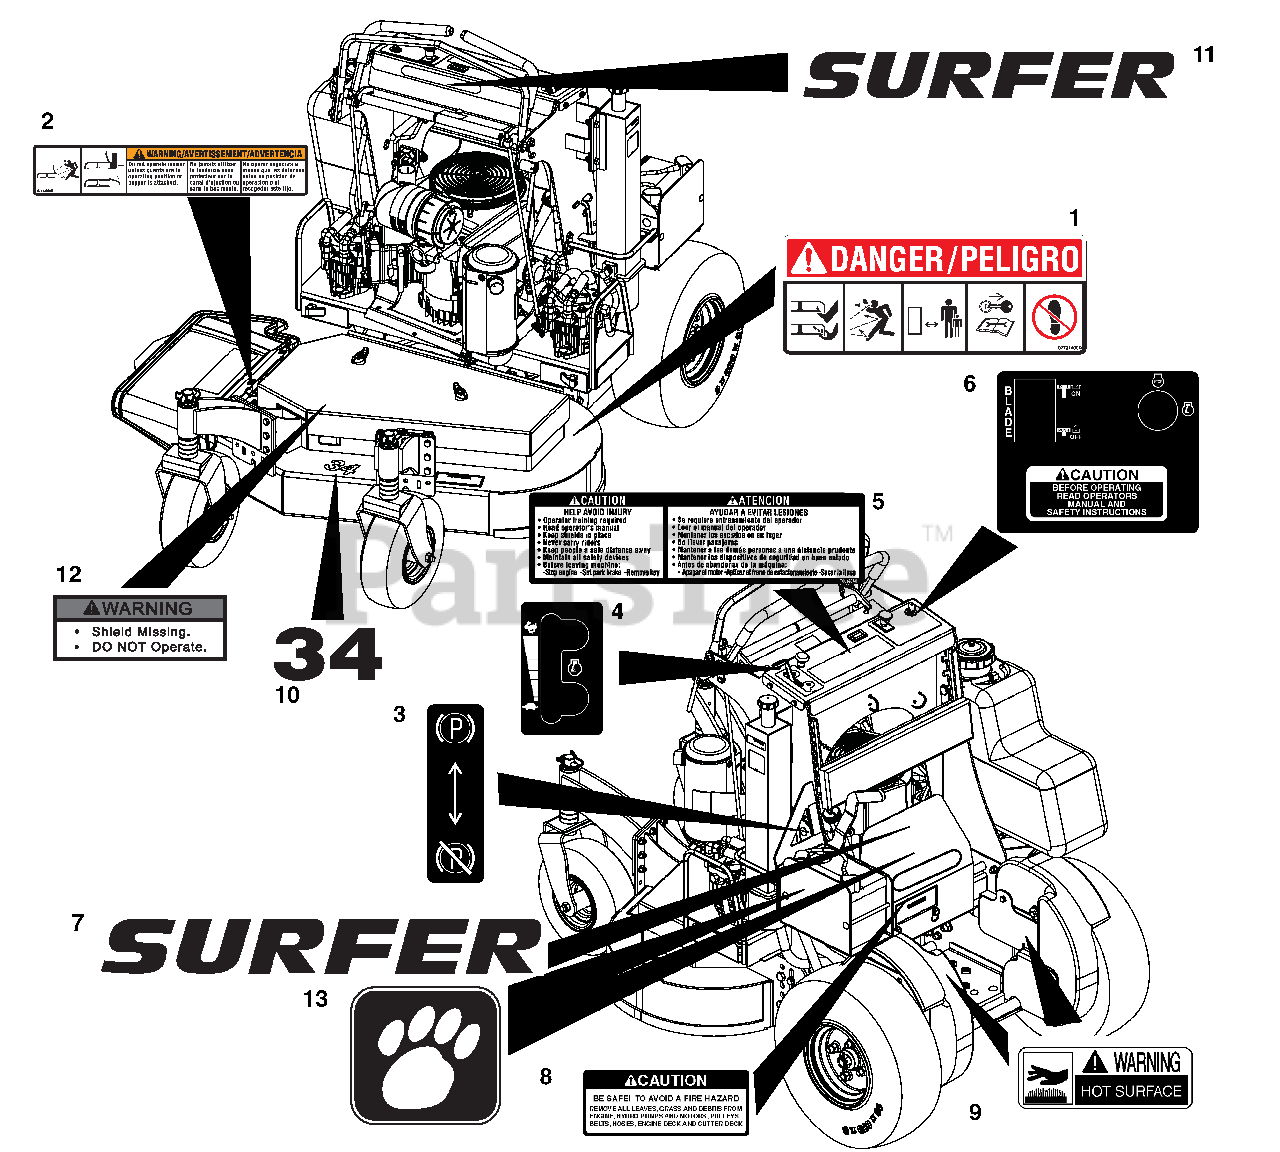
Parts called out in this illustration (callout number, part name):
1	DECAL, MOWER PAN DANGER
2	DECAL, WARNING
3	LABEL - PARK BRAKE DIRECTION
4	DECAL, THROTTLE
5	DECAL, GENERAL CAUTION
6	DECAL, PTO & KEY SWITCH
7	DECAL, SURFER 10.50
8	DECAL, DEBRIS
9	LABEL, WARNING (HOT SURFACES)
10	DECAL, 34 GREAT DANE
11	DECAL, SURFER 7.50
12	DECAL, WARNING - SHIELD
13	DECAL, PAW PRINT
